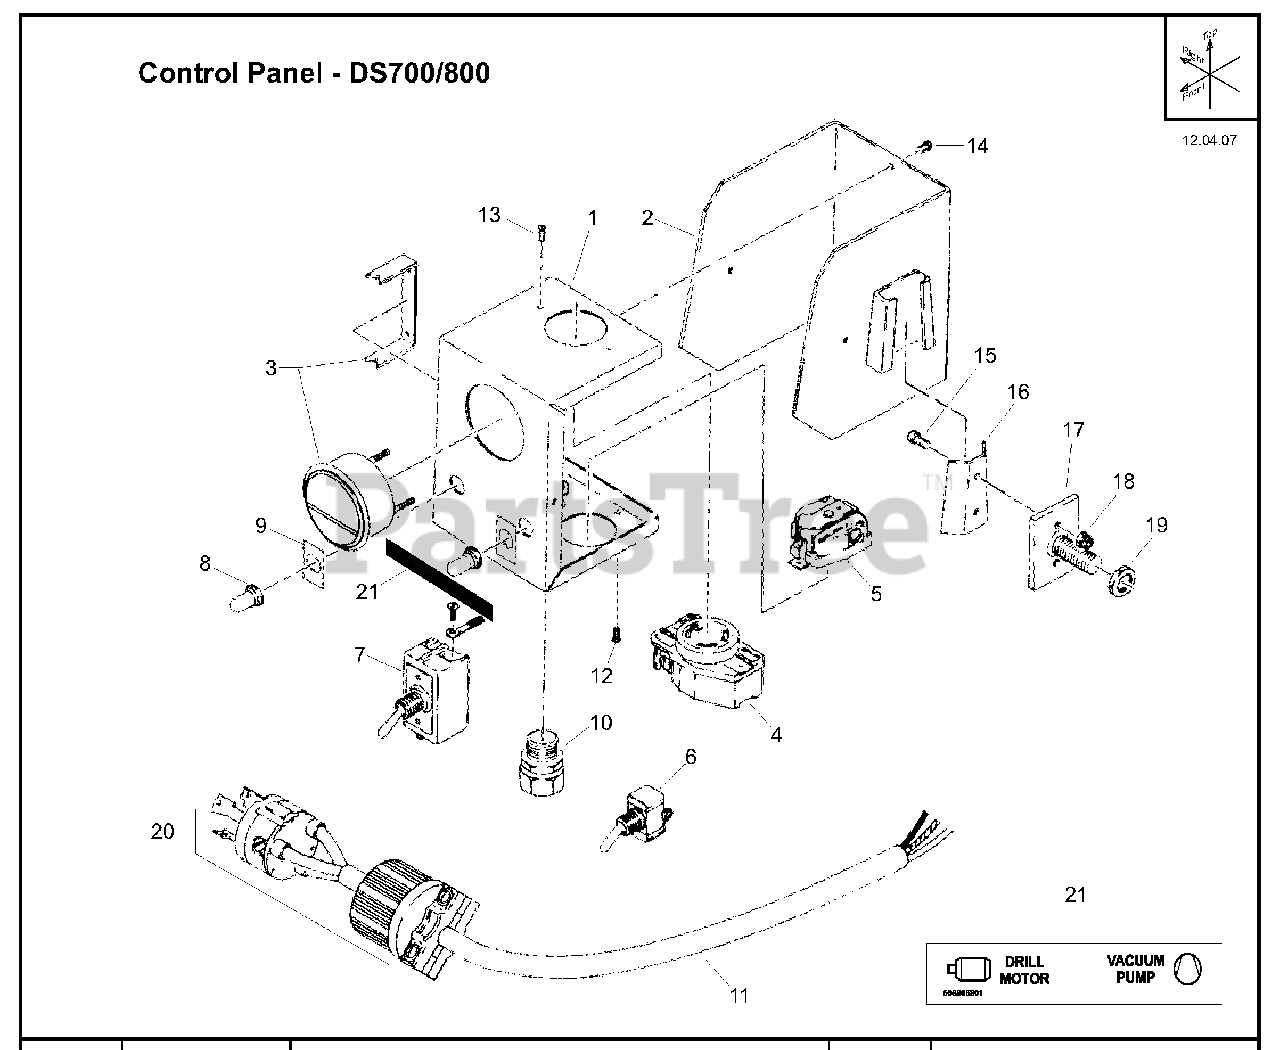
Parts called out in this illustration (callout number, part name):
1	Panel, Front Husq Gray
2	Panel, Back Husq Gray
3	Ammeter, 0-30A
4	Receptacle, 125-20A, Single Twist Lock
5	Receptacle, 125-15A, Single
6	Switch, Toggle
7	Switch, Toggle
8	Boot, Half - Toggle Switch
9	Switch Plate
10	Strain Relief
11	Wire, 12/3 SOW (Per Foot)
12	Capscrew, Button Hd 8-32 x 3/8"
13	Capscrew, Button Hd 6-32 x 3/8"
14	Capscrew, Button Hd 10-32 x 1/4"
15	Capscrew, Soc Hd 1/4-20 x 3/4"
16	Clip, Dovetail - Male
17	Bracket, Mounting Adapter, 1/2-20 UNF
18	Locknut, Fiber .25-20
19	Jam Nut, 1/2-20 UNF
20	Plug, 125V-20A, Twist Lock L5-20P
21	Decal, Control Panel, DS700/800
